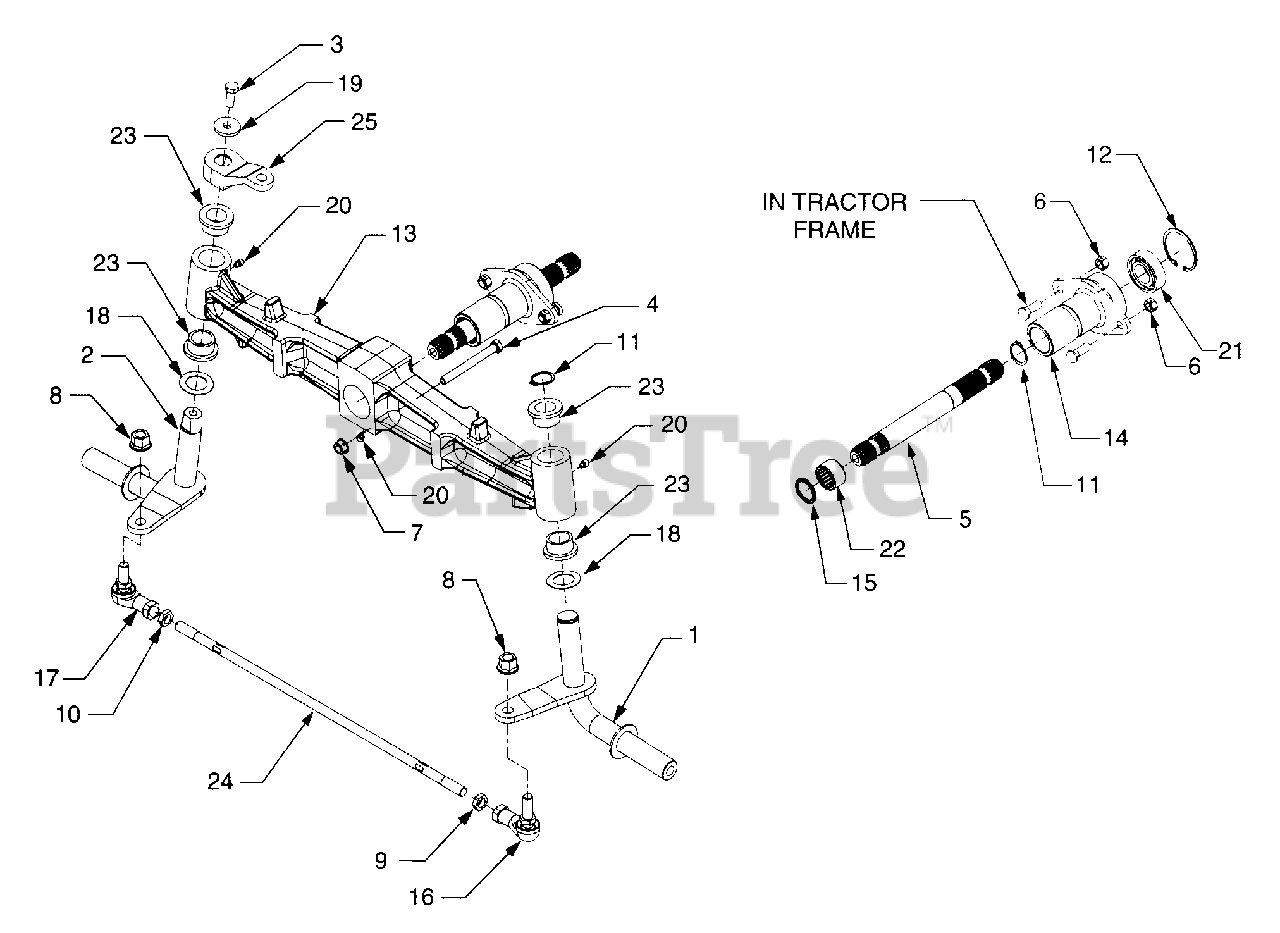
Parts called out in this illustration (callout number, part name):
1	Axle, RH Steering
2	Axle, LH Steering
3	Screw, Hex Cap 3/8-24 x 1.0 GR8
4	Screw, Hex Cap 3/8-16 x 3.5 GR5
5	Shaft, Splined
6	Nut, Hex Center Lock, 3/8-24
7	Nut, Hex Flange Lock, 3/8-16
8	Nut, Hex Flange Lock, M12 x 1.75
9	Nut, Hex - RH, M12 x 1.75
10	Nut, Hex - LH, M12 x 1.75
11	Snap Ring, 1.0 Dia. Shaft
12	Retaining Ring, Internal, 2.0
13	Pivot Axle
14	Axle Carrier
15	Seal, Grease, 1.31 x 1.0
16	Ball Joint, 12MM x 1.75 RH
17	Ball Joint, 12MM x 1.75 LH
18	Washer, Flat, 1.03 x 1.62 x .030
19	Washer, Flat, .406 x 1.25
20	Fitting, Lube, 3/16 Drive
21	Bearing, Ball
22	Bearing, Needle
23	Bearing, Flange
24	Tie Rod, M12 x 1.75 RH & LH
25	Steering Arm
